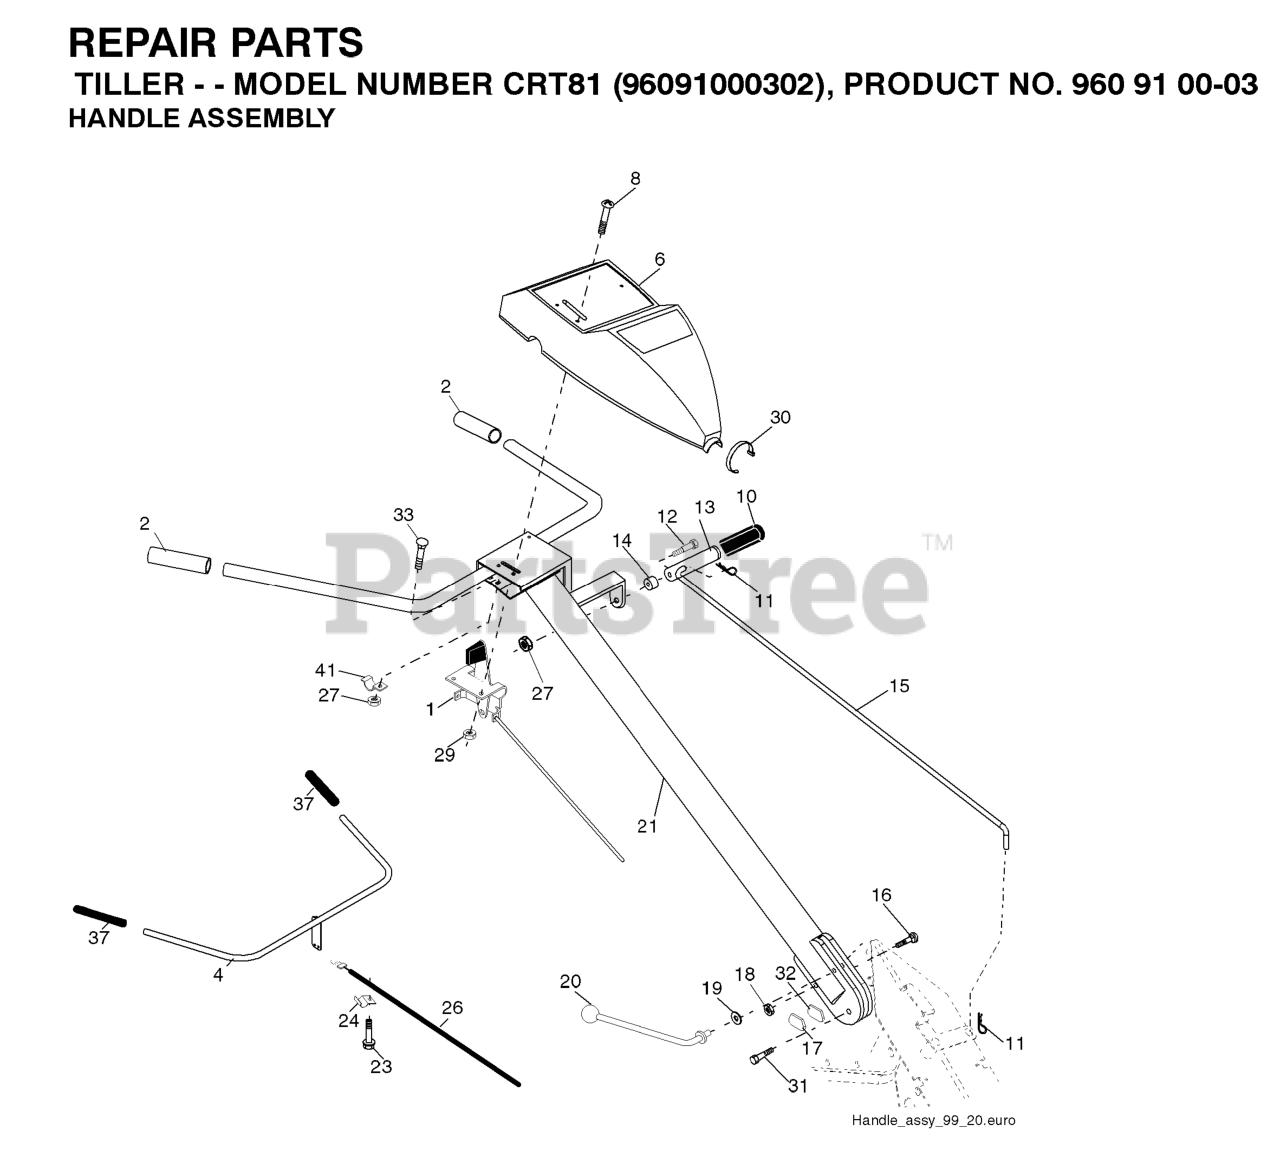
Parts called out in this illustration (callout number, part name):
1	THROTTLE.CONTROL.
2	KIT.GRIP.HANDLE.5.00.BLK.VINYL
4	CONTROL BAR ASSY
6	RP CONTROL PANEL
8	SCREW.PNHD.10-24
10	GRIP T
11	RETAINER M
12	SHOULDER BOLT ST
13	HANDLE.SHIFT.TILLER
14	GROMMET.RUBBER.CRT.TILLER
15	ROD.SHIFT.YARD PRO.UNIVERSAL.
16	BOLT D
17	LOCK.HANDLE.CRT
19	WASHER CRT
20	LEVER.LOCK.CRT
21	REPL BY 532 1805-17
23	TAPPING SCREW
24	CONDUIT.CLIP.PLATED
26	CABLE.CLUTCH
27	NUT T
29	NUT **
30	TIE CABLE CRT
31	BOLT.PIVOT
32	LOCK HANDLE
37	GRIP BAR CRT(1)
41	CLAMP.BAR.CRT.BLACK
